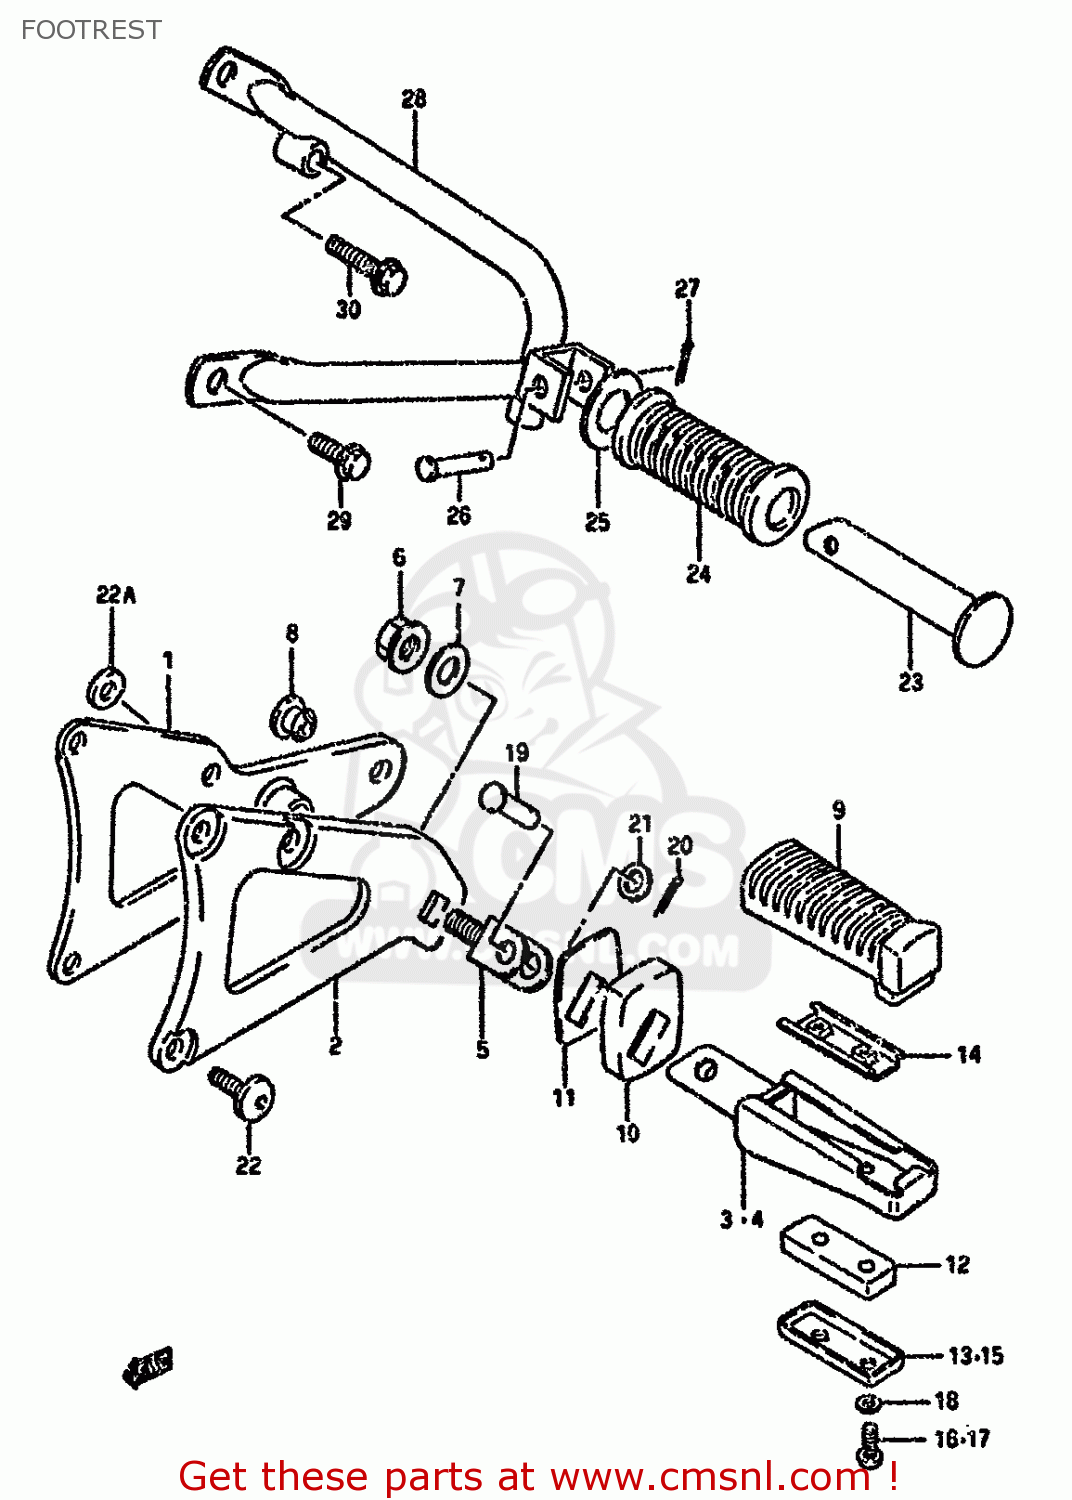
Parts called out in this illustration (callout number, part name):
1	BRACKET, FRONT FOOTREST RH
2	BRACKET, FRONT FOOTREST LH
3	HOLDER,FR FOOTREST,R
4	HOLDER, FRONT FOOTREST LH
5	BOSS,FR FOOTREST
6	NUT
7	WASHER(10.5X20X3.2)
8	CAP
9	RUBBER,FR FOOTREST
10	RUBBER, INNER
11	WASHER,FR FOOTREST
12	BALANCER,FR FOOTREST
13	COVER,FOOTREST BALANCER
14	PLATE,FR FOOTREST
15	PLATE,FR FOOTREST NO.2
16	SCREW
17	SCREW
18	WASHER,LOCK
19	PIN,FR FOOTREST
20	PIN
21	WASHER
22	BOLT(6X18)
22A	WASHER
23	BAR,FOOTREST RUBBER
24	RUBBER,PILLION FOOTREST
25	WASHER (19.5X32X2)
26	PIN
27	PIN
28	HOLDER, PILLION FOOTREST LH
29	BOLT
30	BOLT
